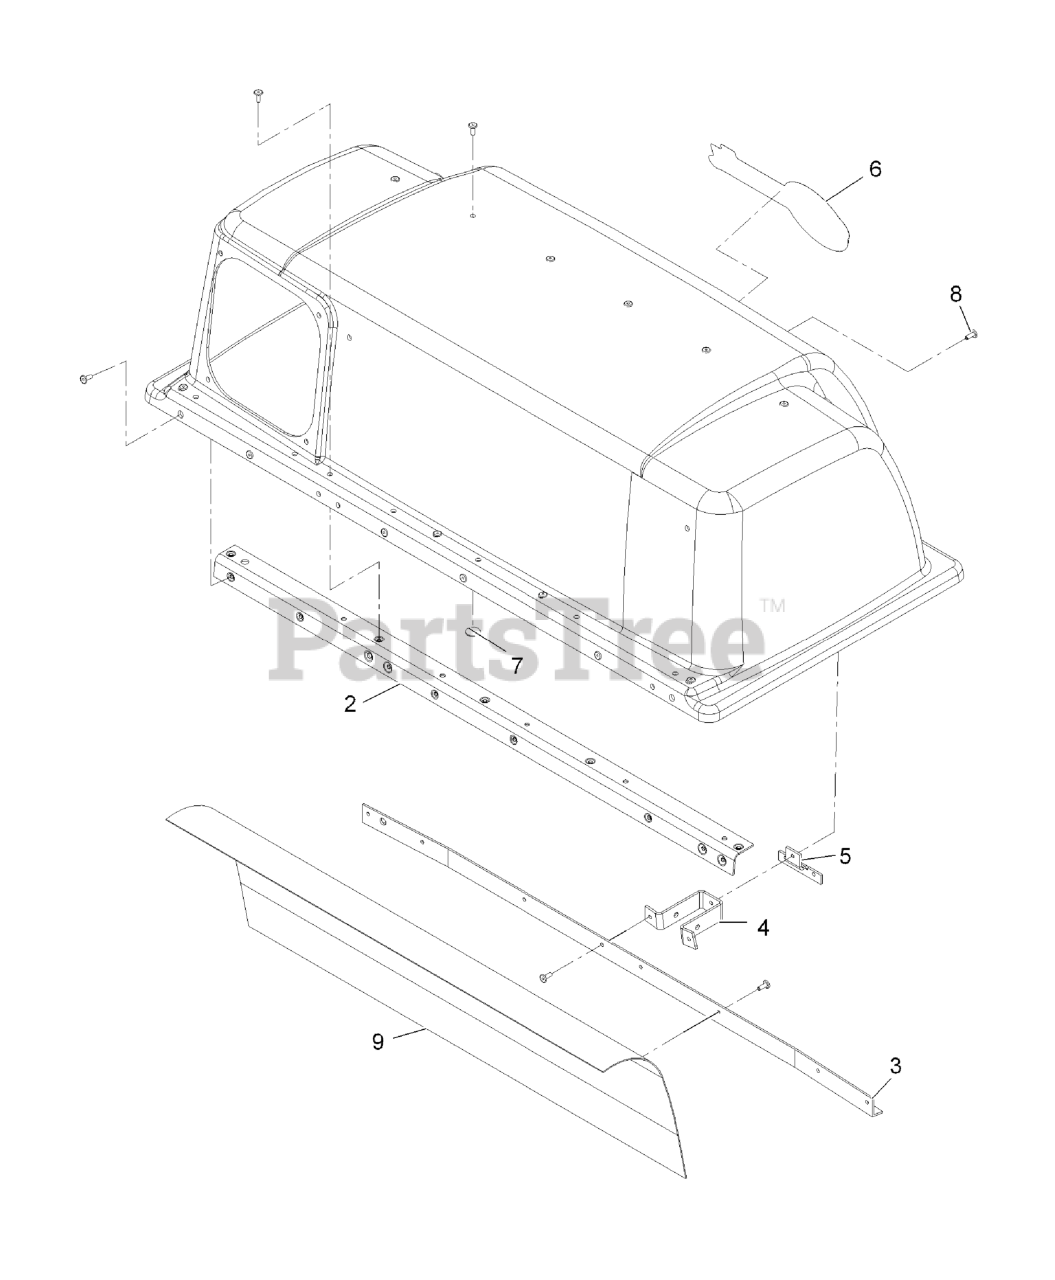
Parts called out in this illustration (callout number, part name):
2	STIFFENER-BAGGER, TOP
3	SUPPORT-SCREEN
4	ANCHOR-LATCH
5	REINFORCEMENT-LATCH
6	DECAL-EXMARK LOGO
7	WASHER-FLAT
8	RIVET-BLIND
9	SCREEN-BAGGER
